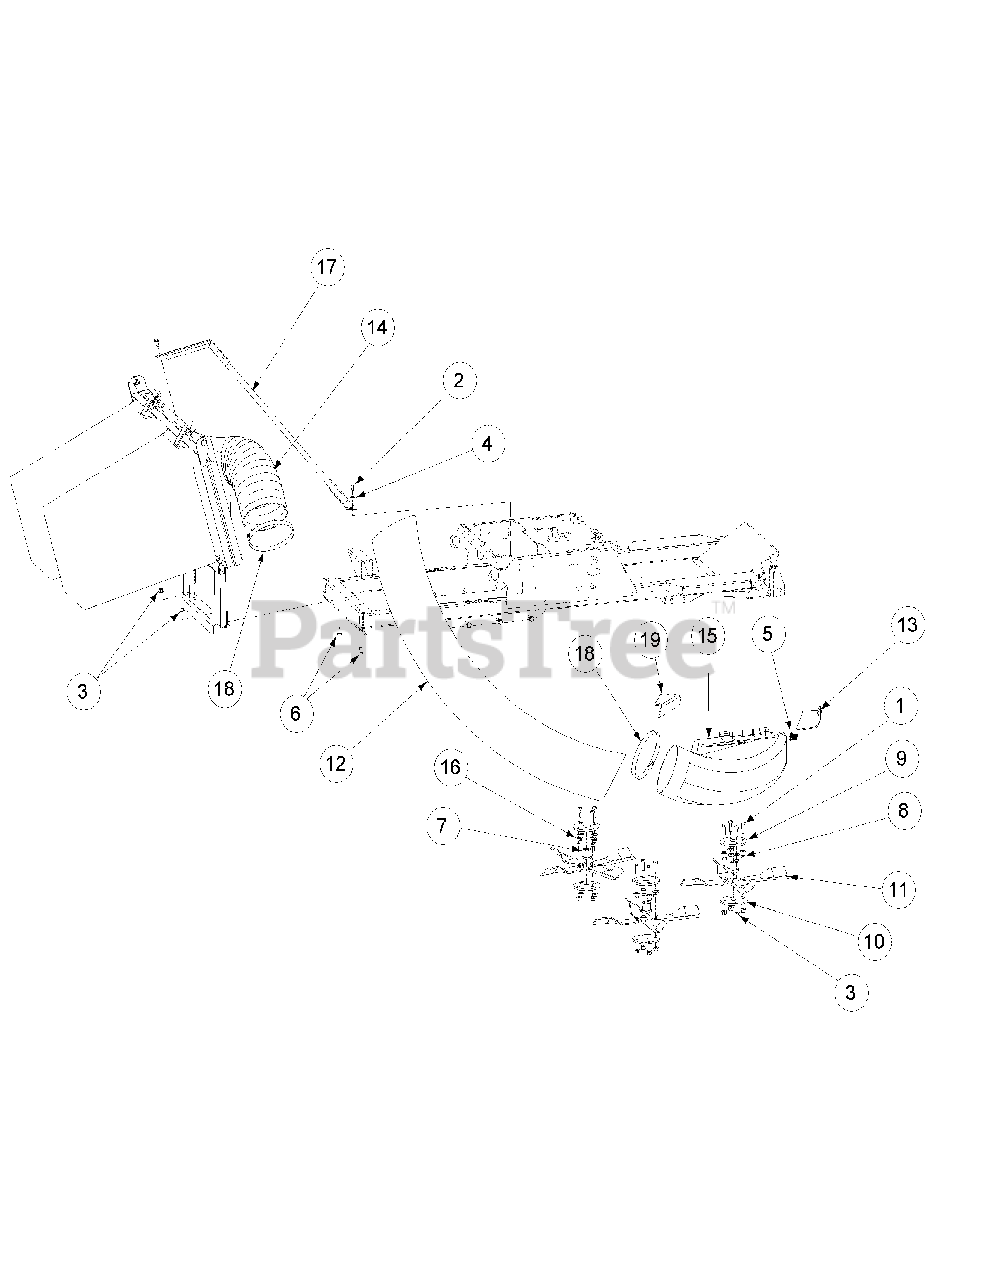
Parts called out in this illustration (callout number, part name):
1	Hex Cap Screw, 3/8-16 x 1-1/4
2	Hex Cap Screw, 5/16-18 x 1.00
3	Flange Lock Hex Nut, 3/8-16
4	Washer, 5/16
5	Carriage Bolt, 3/8-16 x 1.00
6	Hex Cap Screw, 3/8-16, .750
7	Blade Spacer
8	Spacer, .385 ID x .625 OD x .25
9	Mulch Blade Mounting Plate, Top
10	Mulch Blade Mounting Plate, Bottom
11	High Lift Blade
13	MCS Discharge Baffle
14	Double Bagger Assembly
15	Boot Assembly includes:
15	Boot Plate
15	Pop Rivet
16	Washer, 1" OD x .625" ID x .048
17	Strut Support Weldment
19	Chute Discharge Baffle
